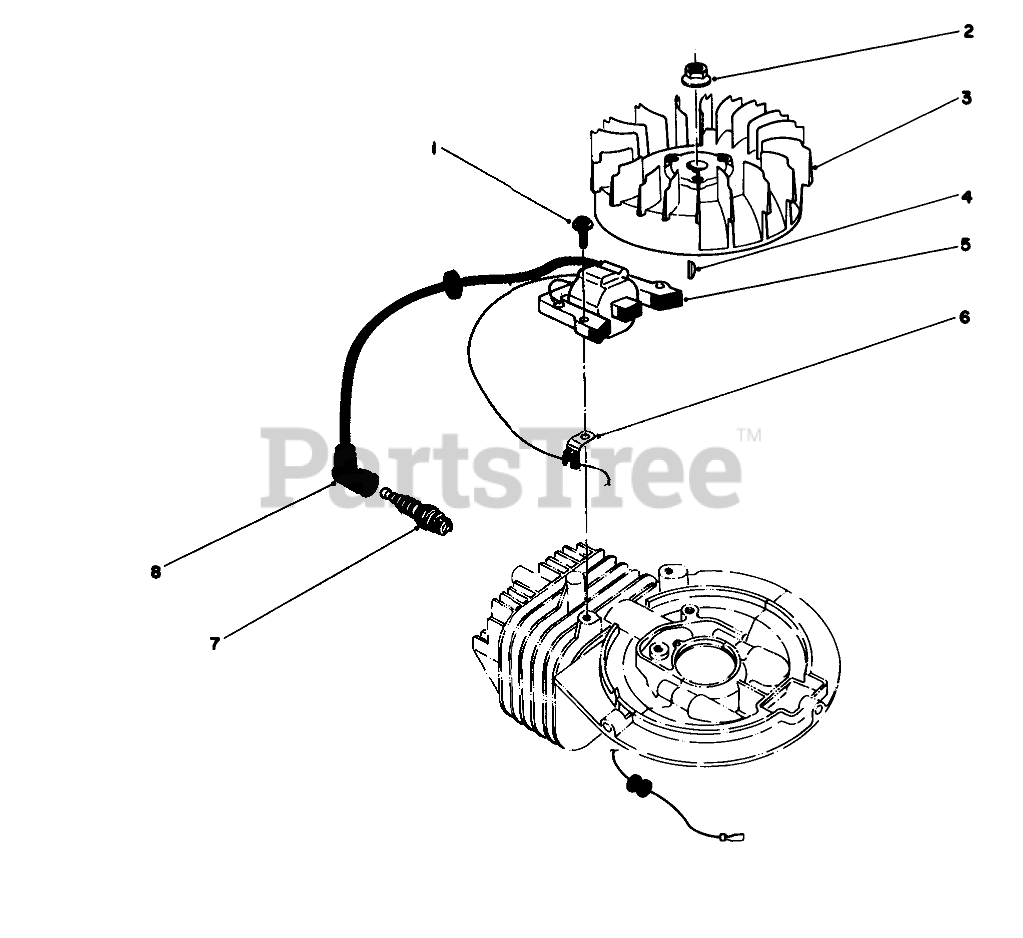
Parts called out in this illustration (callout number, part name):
1	Allenhead
3	FLYWHEEL
5	COIL-MAGNETO
6	CLAMP
7	Sparkplug
8	CAP-SPARKPLUG
